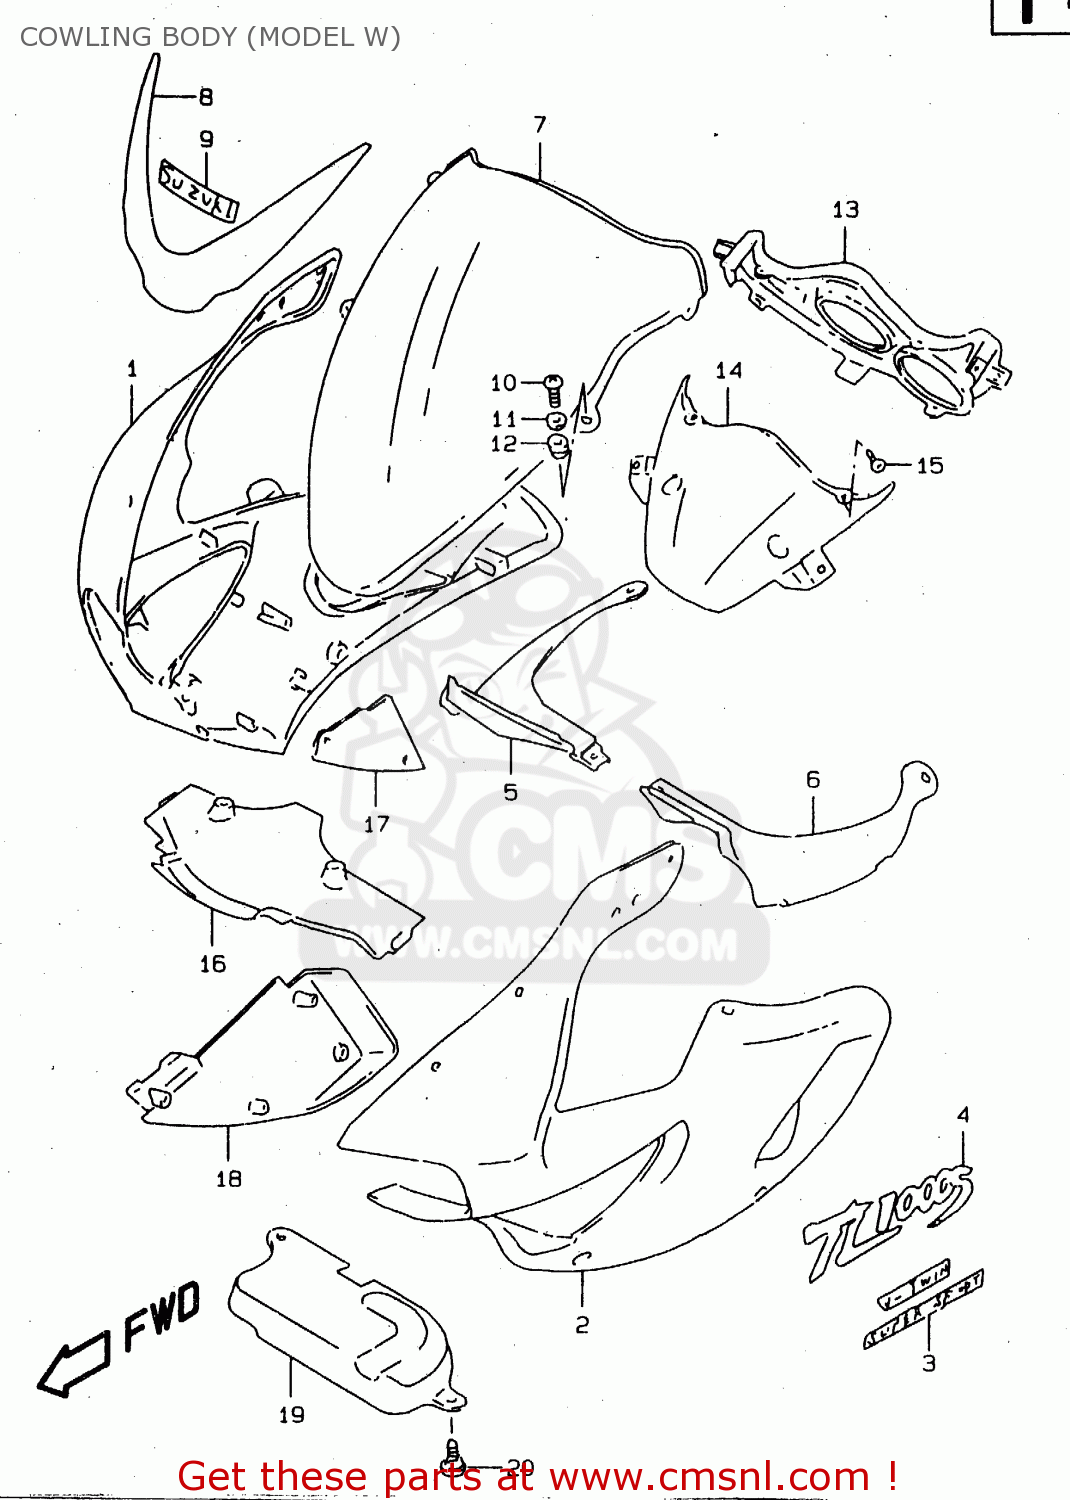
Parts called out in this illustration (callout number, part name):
1	COWLING,SIDE,R(RED)
2	COWLING,SIDE,L(RED)
3	EMBLEM,COWLING SIDE
4	EMBLEM,COWLING
5	PANEL,SIDE,R
6	PANEL,SIDE,L
7	WINDSCREEN(SILVER)
8	TAPE,WINDSCREEN
9	EMBLEM(SILVER)
10	SCREW(5X14)
11	WASHER
12	NUT
13	PANEL,METER
14	PANEL,FR
15	CLIP(BLACK)
16	COWLING,CTR LWR
17	COWLING,INNER,R
18	COWLING,INNER,L
19	COVER,COWLING FR LWR
20	BOLT
